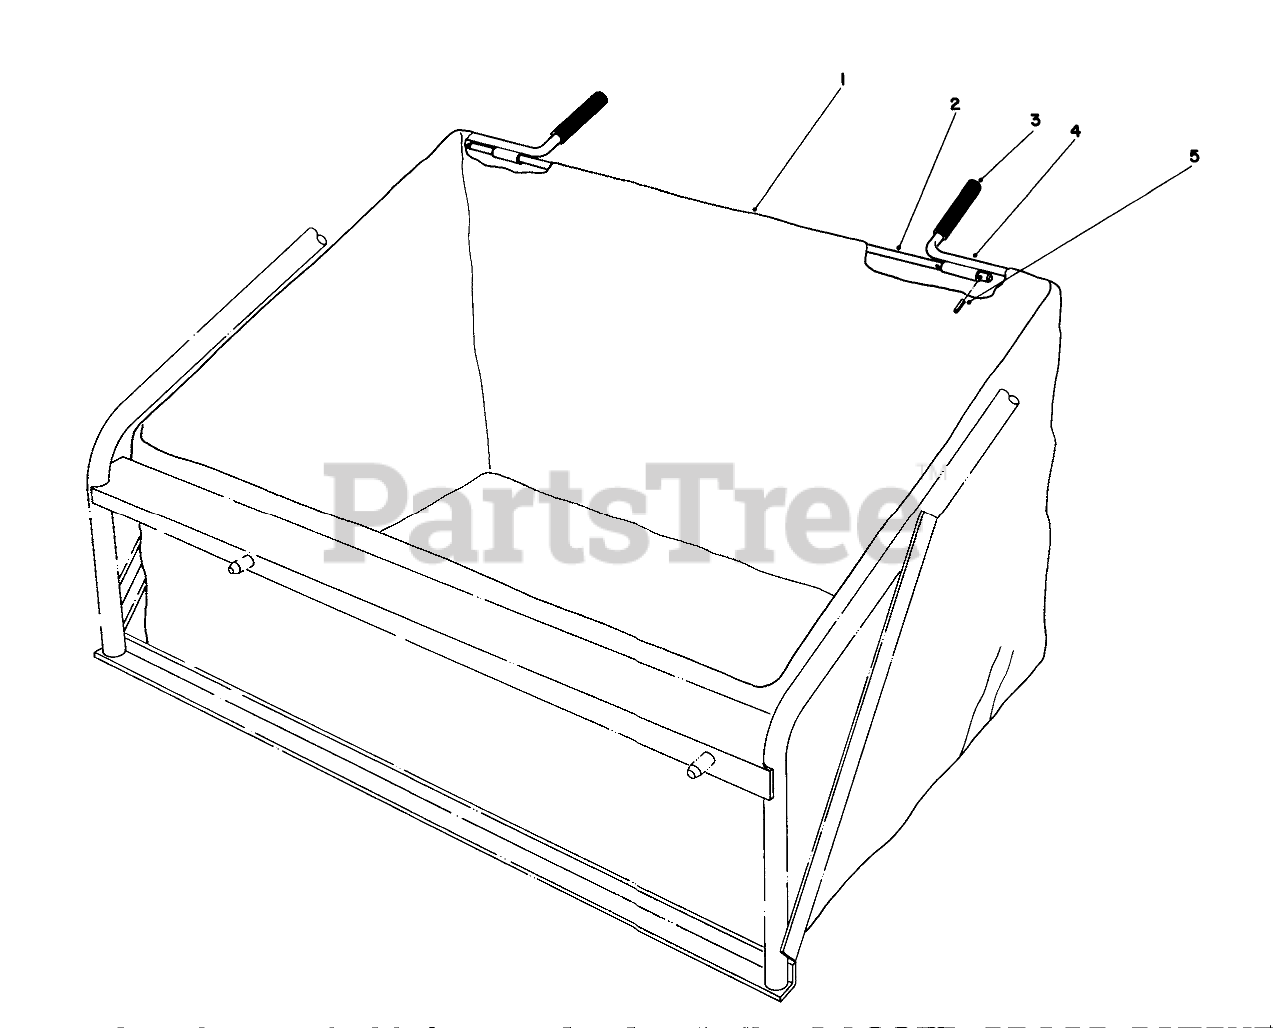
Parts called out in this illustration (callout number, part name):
1	Bag-Leaf Catcher
2	BAG FRAME ROD
3	BAG HANDLE GRIP
4	BAG FRAME WA B
5	PIN-ROLL
